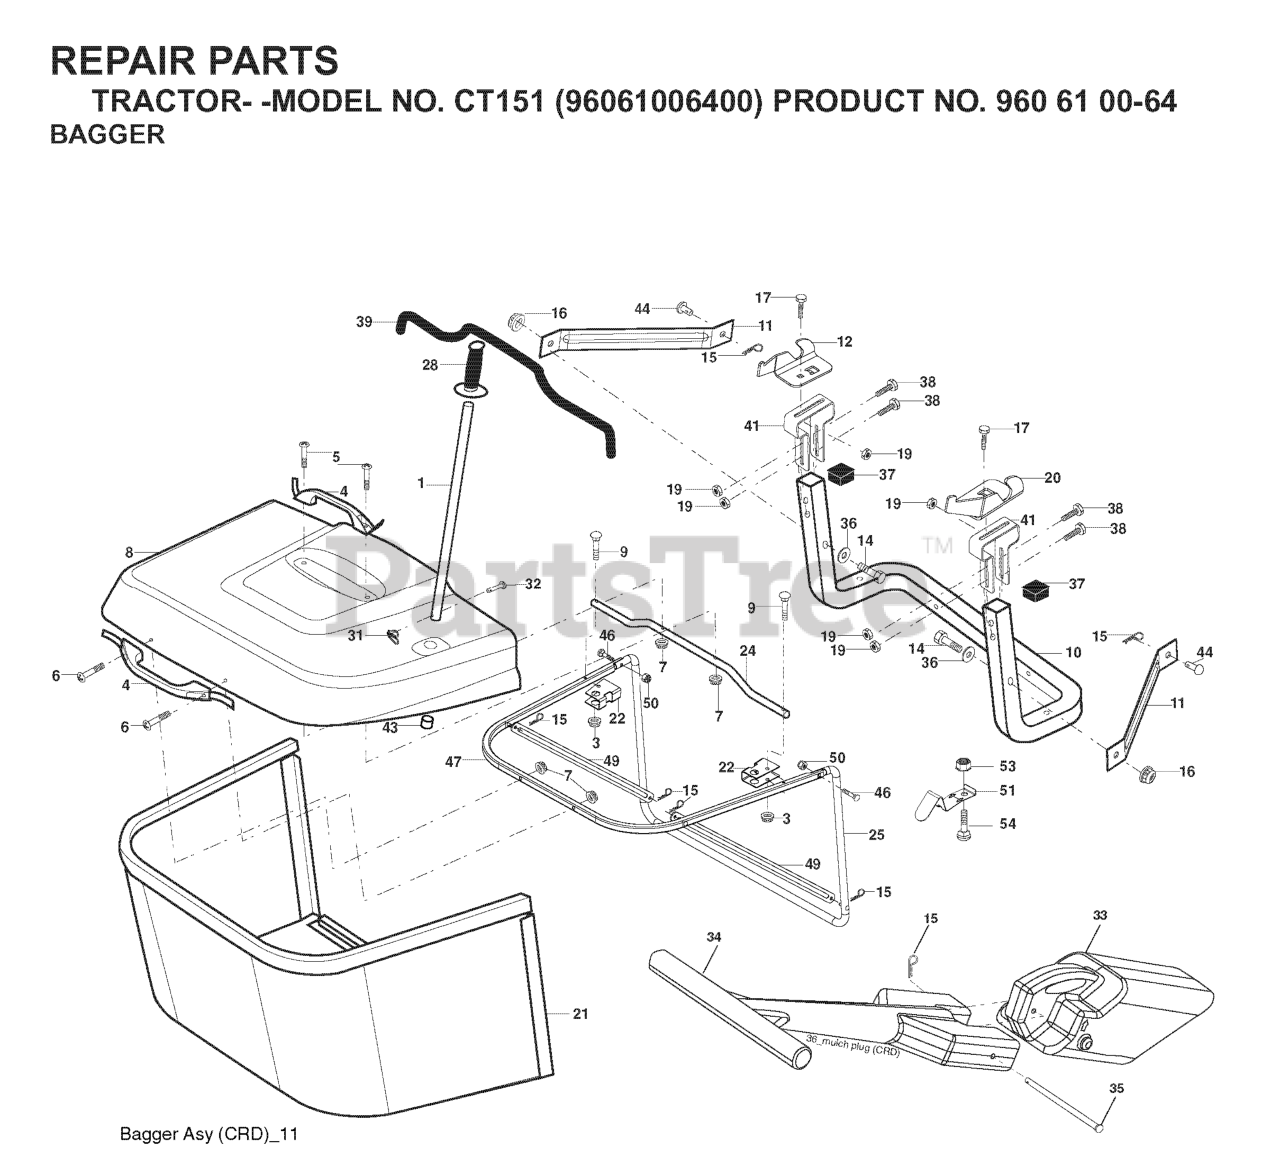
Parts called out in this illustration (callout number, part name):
1	TUBE HANDLE
3	NUT T
4	HANDLE.BAGGER.W/LVRS.BLK.CRD
5	SCREW.PAN.HEAD
6	REPL BY 532 75 00-29
8	COVER.PNT.BGR.CRD.WSLOTS.MS668
9	Bolt Carriage 1/4-20 x 2.25d x Gr.5
10	TUBE
11	BRACKET.SUPPORT.UPPER.BAG.CRD
12	BRKT PIVOT
14	BOLT-HEX EAK
15	RETAINER-SPRNG RB
16	NUT LOCK FLG 3/8-16 UNC
17	RP BOLT 5/16-18 X3/4 ZN/YEL GR
19	NUT LOCK HEX FLANGE 5/16-18
20	BRKT.PIVOT.RH.CRD
22	BRKT.SIDE.BAG.CRD
24	TUBE.PIVOT.BAG.CRD.BLACK
25	PIPE
28	GRIP.HANDLE.BLACK
31	RETAINER CLIP
32	RIVET,DRILLED
33	PLUG.MULCHER.92 CRD
34	HANDLE.MULCHER.92.CRD (2 2)
36	WASHER
37	Plug Support Bagger CRD
38	BOLT.5/16-18X2.5
39	SEAL.TRIM.37'
41	BRKT.VERT.ADJ.BAGGER.CRD
43	PLUG, TUBING END
46	BOLT.CARRIAGE.5/16-18
47	PIPE
49	ROD
50	NUT.71038.31-18.HEX.NYLOCK
51	LATCH
53	NUT
54	BOLT
